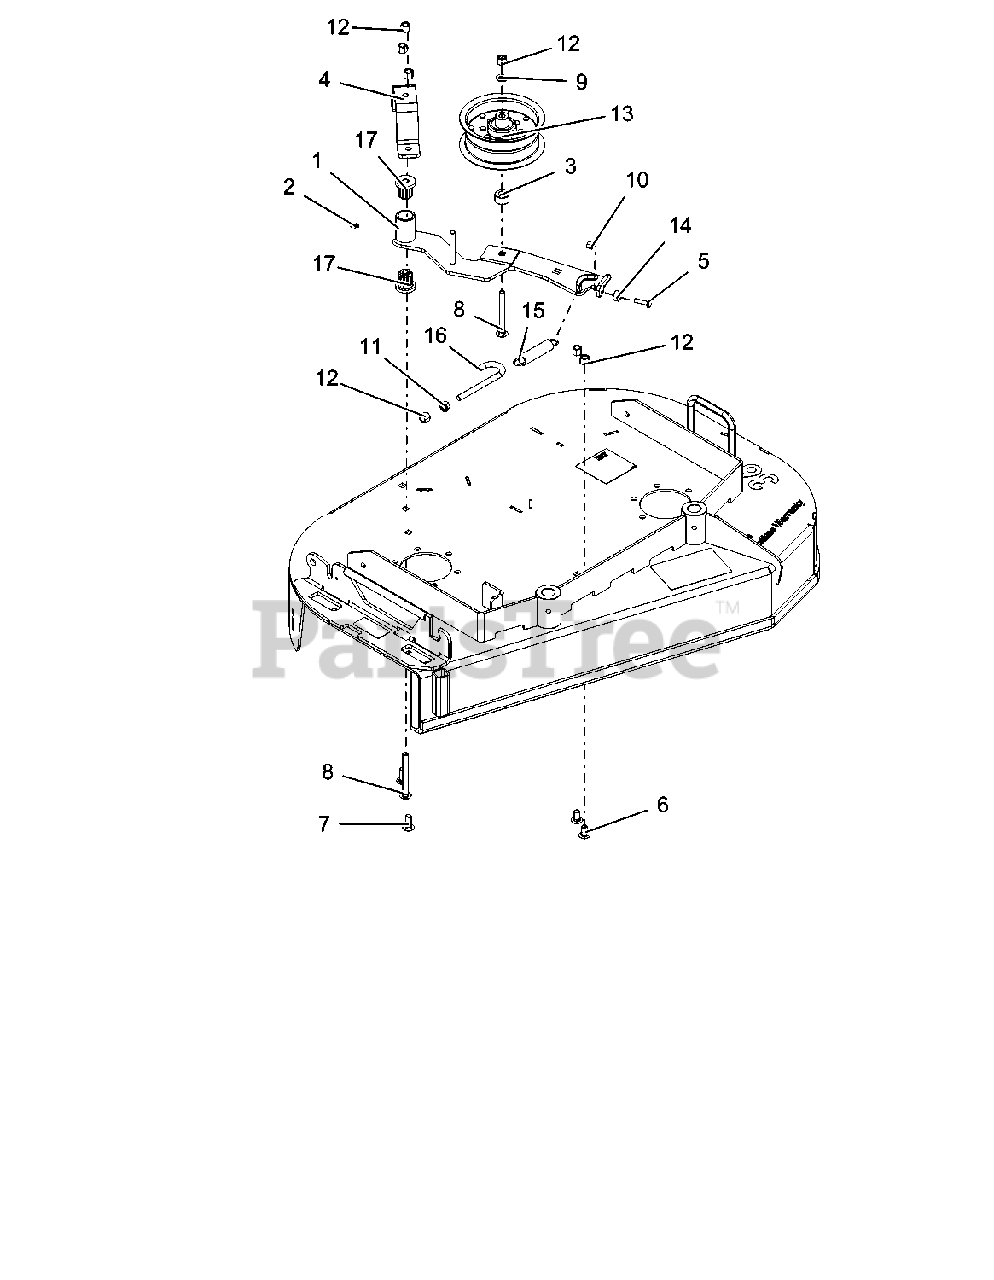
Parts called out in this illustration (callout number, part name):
1	WLDMT, IDLER
2	FTG, 1/4-28 STRGT GREASE ZERK
3	SPACER, .437X1.00X.58 SMLS
4	STRAP, IDLER 36 (BLACK)
5	BLT-HEX .25-20X1.00 GR5 YWZC
6	BLT-RHDSSQNK .38-16X.75 G5YZ
7	BLT-RDHDSHSQNK.38-16X1.0 G5YZ
8	BLT-RDHDSQNK .38-16X3.50 G5 YWZC
9	WSHR-FL-STL.406X.812X.065 YWZ
10	NUT-LK-NYL .250-20 YWZC
11	@NUT-SPNLK-FLG .375-16 YWZC
12	NUT-LK-NYL .38-16 YWZC
13	PULLEY, FLAT 5.00X2.36X.375
14	BRG, BAL .250 X .688 X .313
16	J-BOLT, 3/8-16 X 4.00 Y
17	BRG, FLG M10XM25XM27 FLUTED
